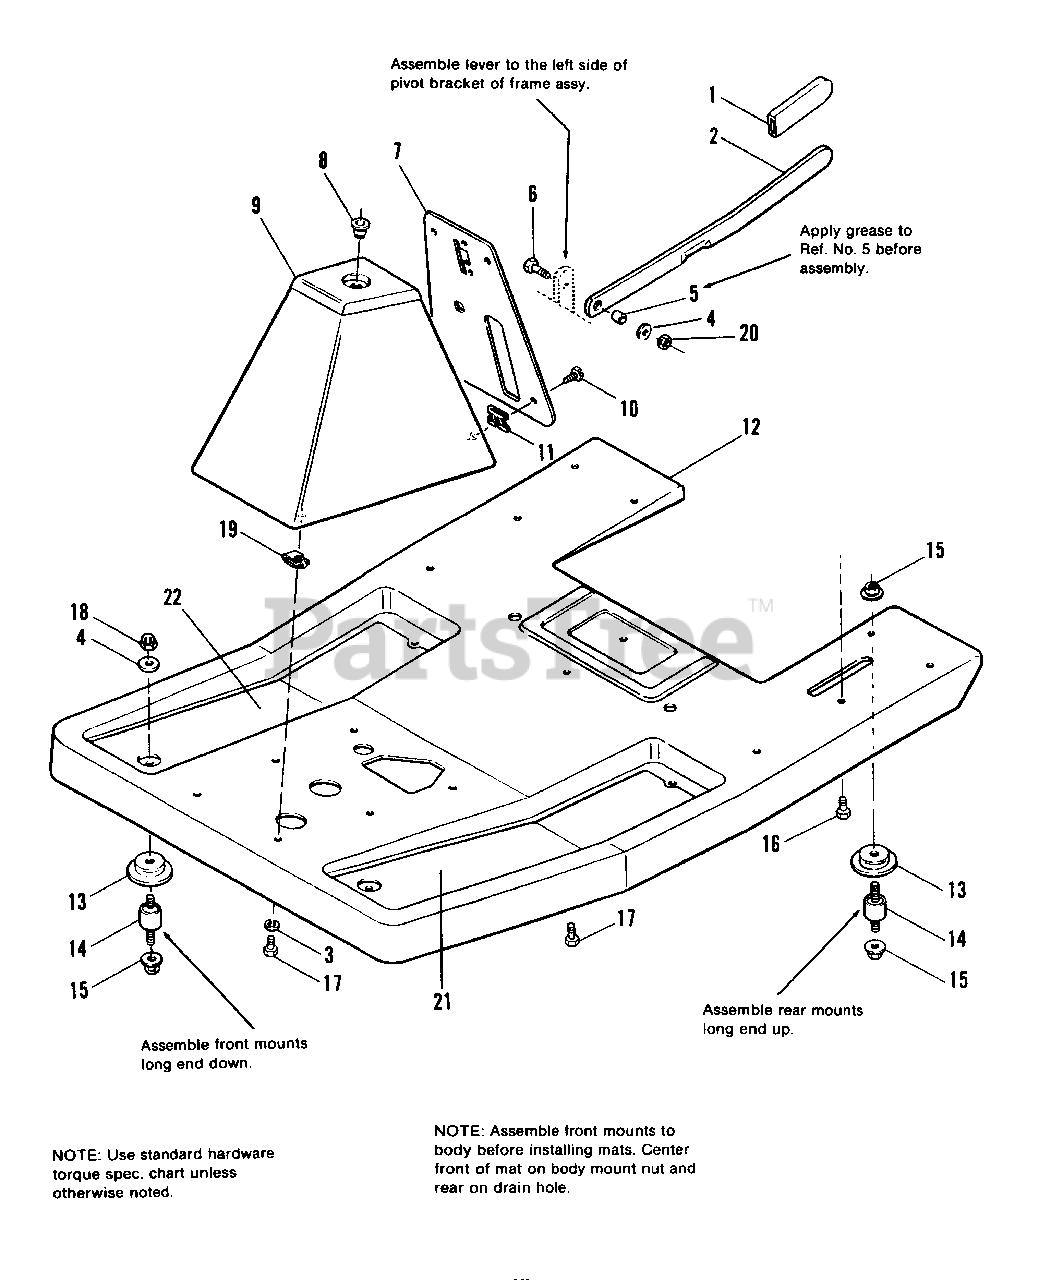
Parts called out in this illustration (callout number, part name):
1	GRIP, Lever
2	LEVER, Lift
3	LOCKWASHER, 5/16
4	WASHER, Plain, 5/16
6	CAPSCREW, Hex, 5/16-18 x 1
7	PANEL, Steering Column
8	BUSHING, Nylon
9	STEERING COLUMN ASSY.
10	SCREW, Hex, Thd. Forming, #10 x 1/2
11	U-NUT, #10 x 1/2
12	BODY, Front
13	RESTRAINER
14	CONNECTOR, Cushion
15	LOCKNUT, Flange, Whiz, 5/16-18
16	CAPSCREW, 5/16-18 x 5/8
17	CAPSCREW, Hex Hd., 5/16-18 x 3/4
18	NUT, Acorn, 5/16-18
19	NUT, Speed, 5/16-18
20	LOCKNUT, Hex, 5/16-18
21	MAT, Foot, L.H.
22	MAT, Foot, R.H.
